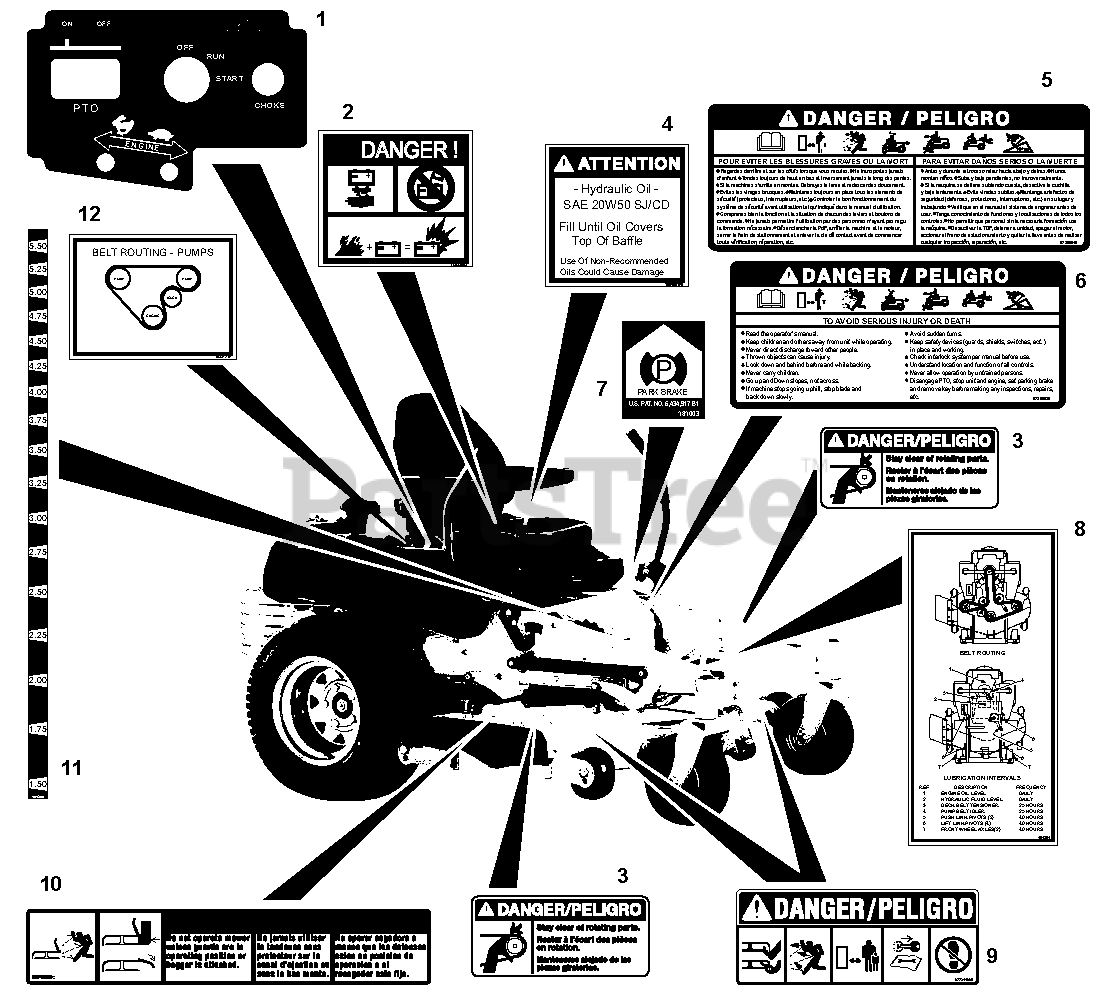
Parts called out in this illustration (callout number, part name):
1	Decal, Control Panel
2	Decal, Danger - Battery
3	Decal, Danger Belt Rotation
4	Attention, Hydraulic Reservoir
5	Decal, Safety French/Spanish
6	Decal, Safety English
7	Decal, Park Brake
8	Decal, Belt RT and Lub Instruction
9	Decal, Mower Pan Danger
10	Decal, Warning
11	Decal, HOC Index
12	Decal, Pump Belts
